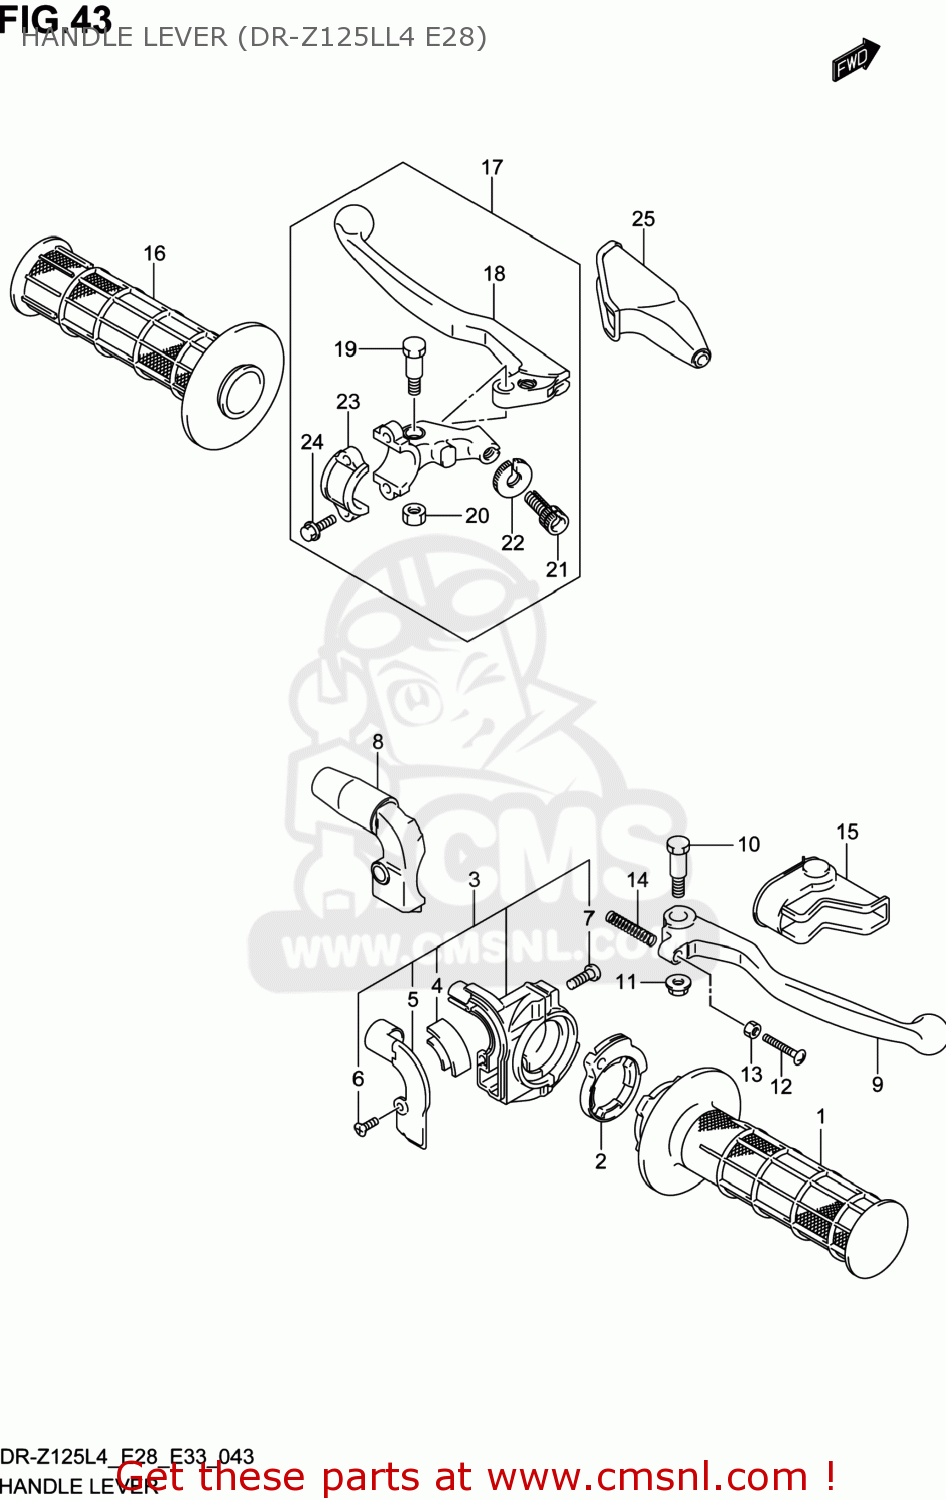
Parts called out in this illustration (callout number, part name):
1	GRIP,THROTTLE
2	ROTER,THROTTLE
3	CASE ASSY,THROTTLE
4	GUIDE
5	COVER
6	SCREW
7	SCREW
8	COVER,THROTTLE CASE
9	LEVER,BRAKE
10	BOLT,BRAKE LEVER
11	NUT
12	BOLT,ADJUST
13	NUT
14	SPRING,RETURN
15	COVER,BRAKE LEVER
16	GRIP,L
17	LEVER ASSY,CLUTCH
18	LEVER,CLUTCH
19	BOLT,LEVER PIVOT
20	NUT
21	ADJUSTER,WIRE
22	NUT,LOCK
23	BRACKET,CLUTCH LEVER HOLDER
24	BOLT,BRACKET
25	COVER,CLUTCH CABLE DUST
